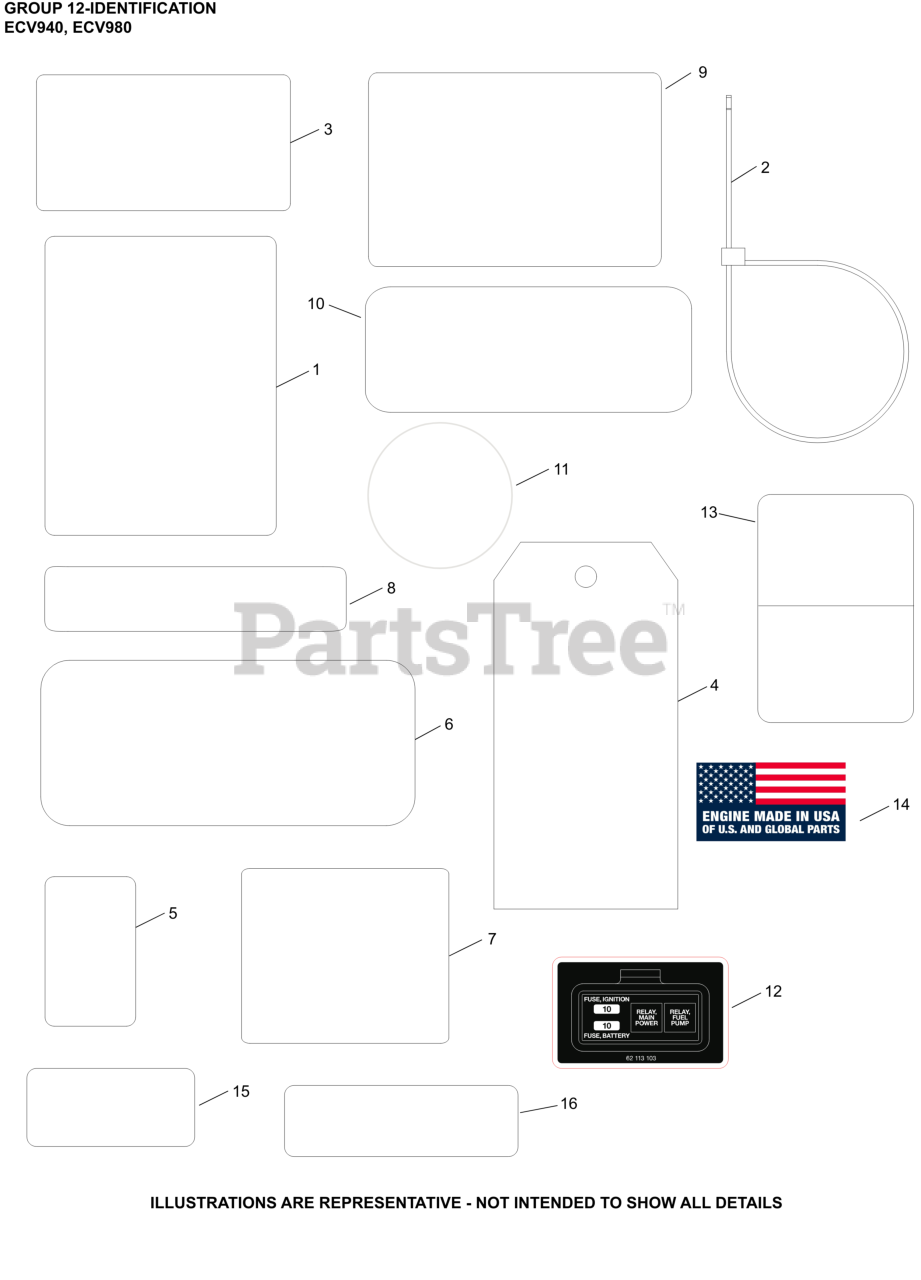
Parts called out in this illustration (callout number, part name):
1	LABEL, CLEAR LAMINATION
7	DECAL HDAC, ECV980/999cc
13	HOT SURFACE DECAL
14	DECAL, USA
